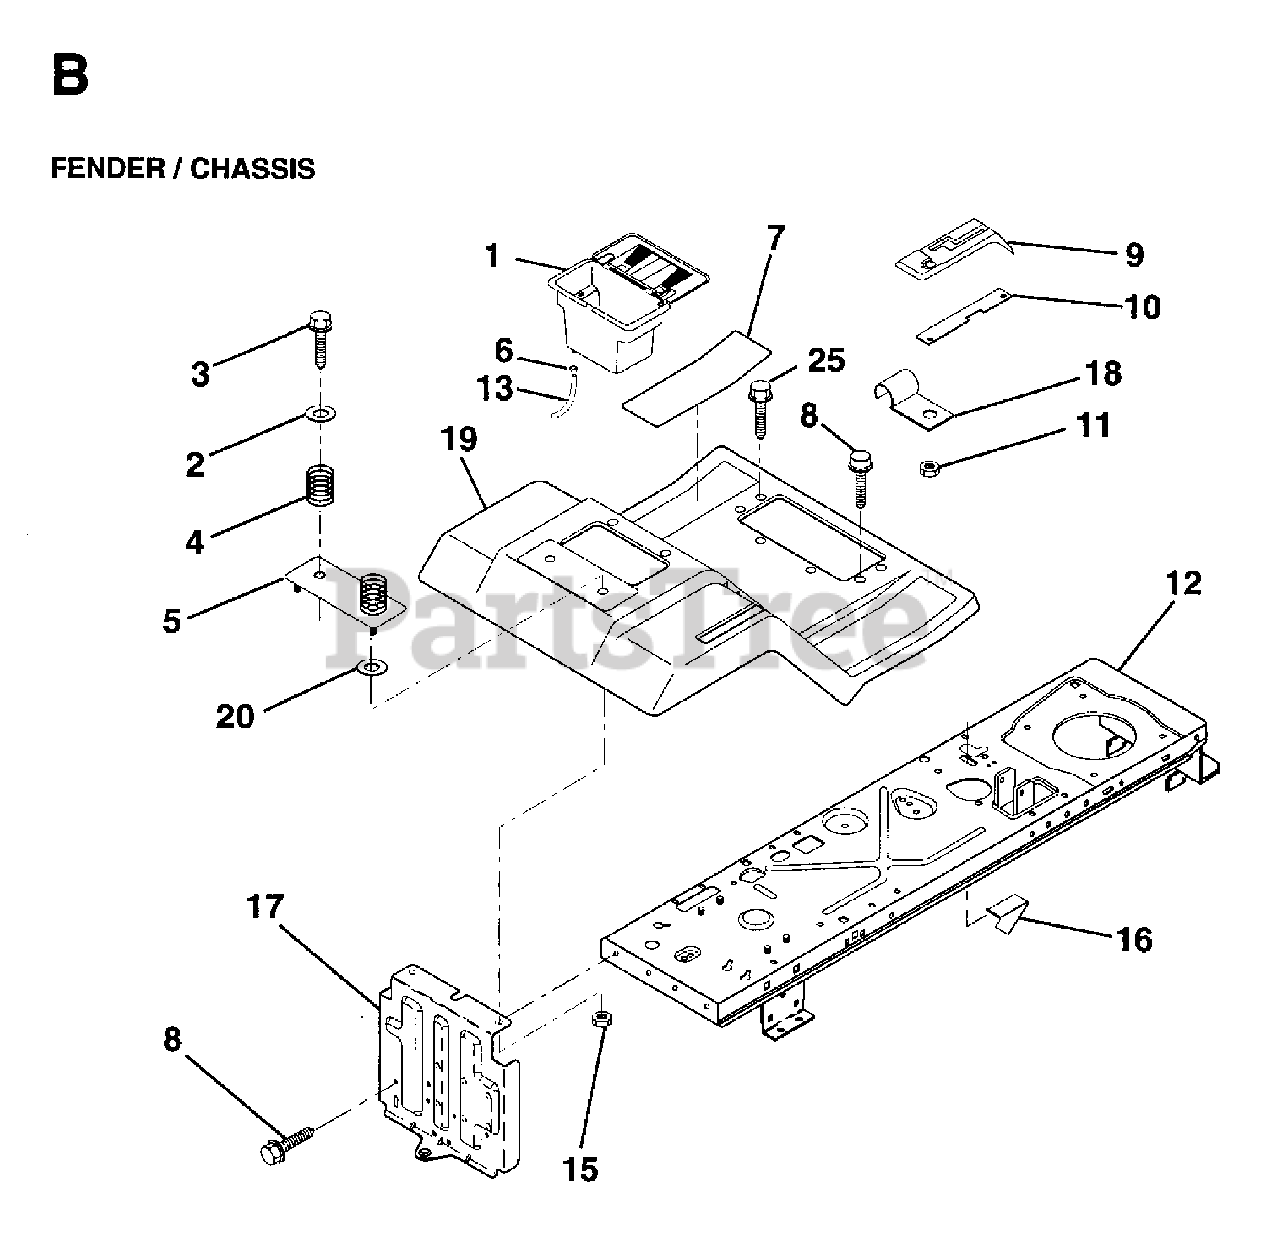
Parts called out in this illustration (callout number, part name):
1	BATTERY CASE
3	SCREW
4	SPRING COMPRESSION
6	HOSE CLAMP T
7	PAD FOOTREST
8	SCREW
10	BAR, SHIFT LOCK
13	TUBE BATTERY DRAIN
18	CLIP,INSULATOR
20	WASHER
